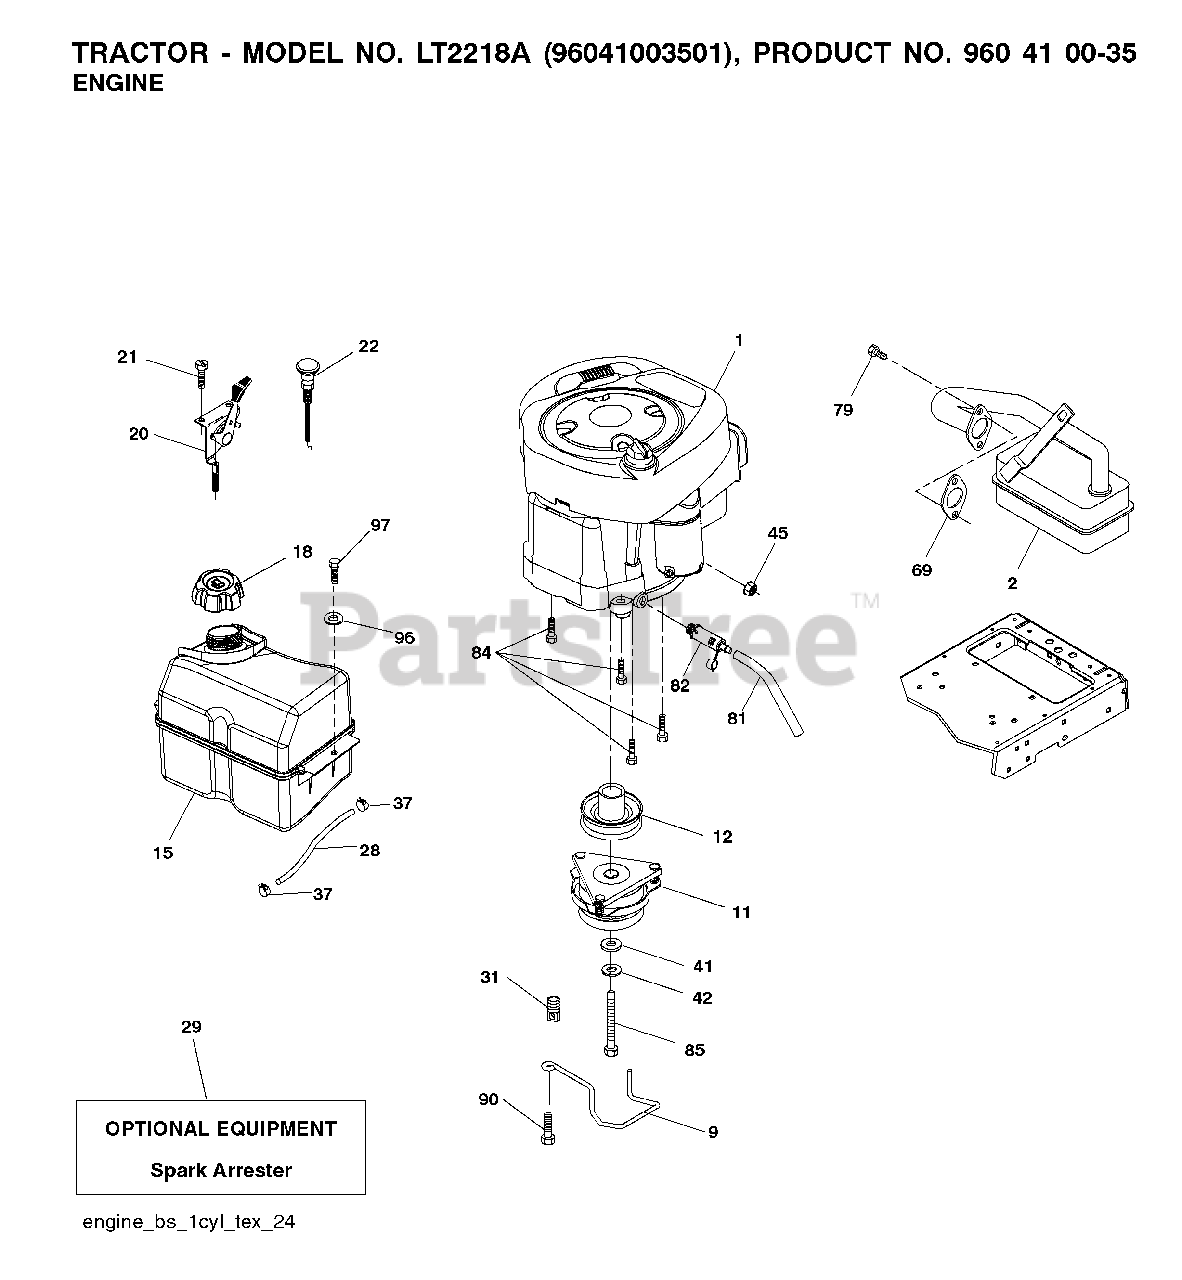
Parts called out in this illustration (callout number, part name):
9	KEEPER.BELT.ENGINE.4.2
11	CLUTCH
12	PULLEY.ENGINE.TUFFTORQ
15	TANK FUEL
18	FUEL CAP
20	CONTROL.TH/CK.C.
21	SCREW
28	LINE.FUEL.20
29	ARRESTER SPARK (OPTIONAL)
31	PUSH CLIP
37	HOSE CLAMP
42	LOCKWASHER
45	NUT
69	REPL BY 532 27 22-93
79	SCREW.SOCKET HD.5/16-1
81	TUBE, DRAIN OIL ASM.
82	PLUG DRAIN OIL EASY
84	SCREW.3/8-16
85	BOLT HEX 7/16-20X4-1/4"
90	SCREW 3/8-16X1
97	SCREW HEXWSHR 1/4-20X3/4
